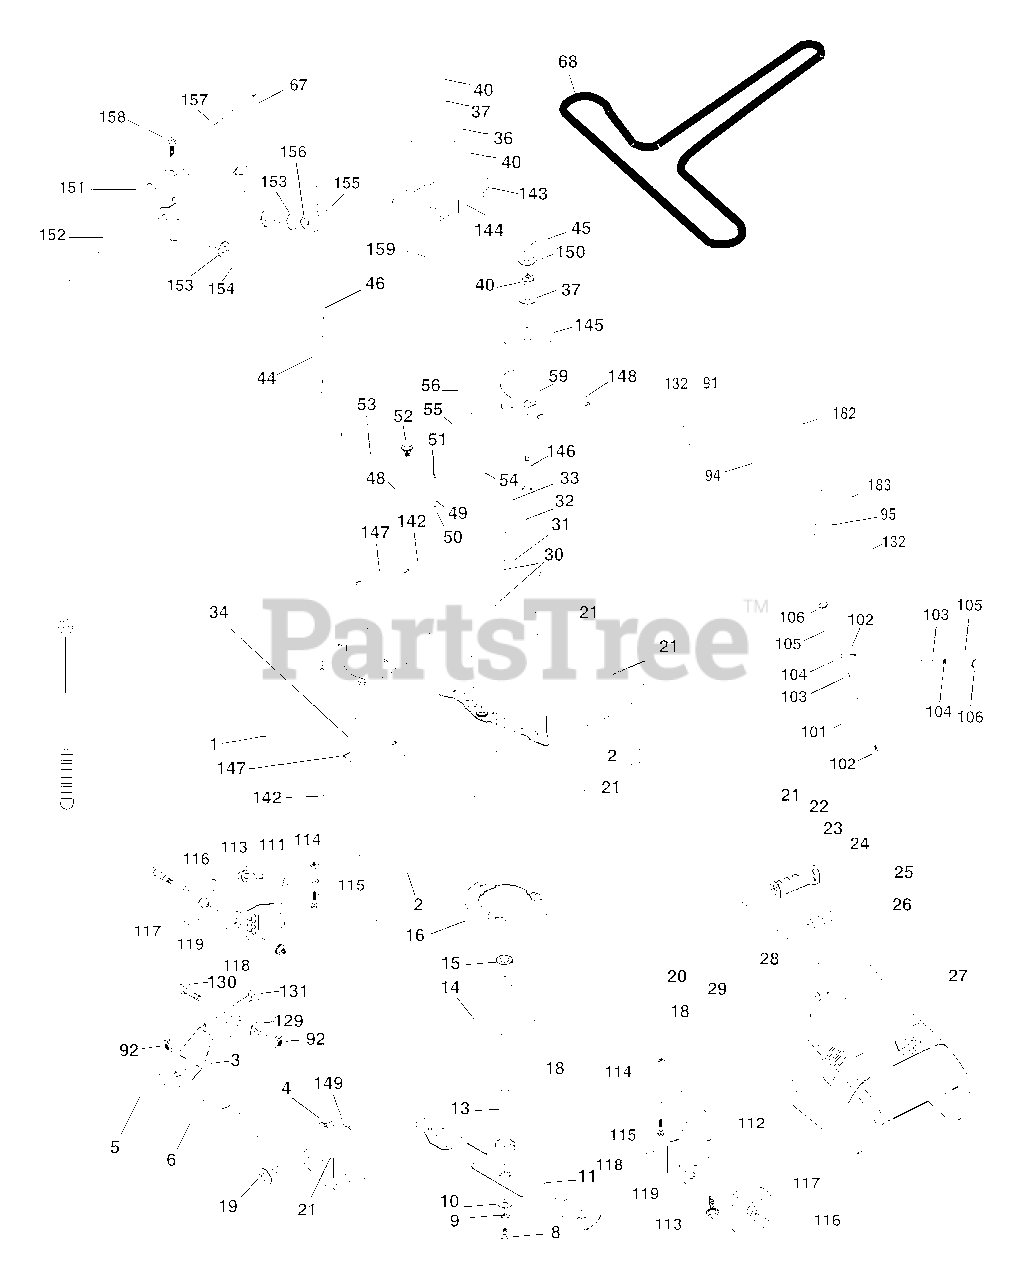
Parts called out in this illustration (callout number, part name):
1	Mower Deck Assembly, 42"
2	Bolt
3	Bracket Asm Fr. Sway Bar 3/42
4	Bracket Asm Deck 42" Sway Bar
5	Retainer Spring
6	Bar Sway Deck
8	Bolt 3/8-24 x 25 Grade 8 patched
9	Washer, Lock
10	Washer, Hardened
11	Blade, Mulching 42" Std
11	Blade Mower 42" Hi-Lift Std
13	Shaft Assembly, Mandrel, Vented
14	Housing, Mandrel, Vented
15	Bearing, Ball, Mandrel
16	Stripper, Mandrel Deck
18	Bolt, Carriage 5/16-18 x 5/8
19	Bolt, Shoulder
20	Baffle, Vortex
21	Nut
22	Stiffener Bracket
23	Bracket, Deflector Mower 42"
24	Cap, Sleeve 80 x 112 Blk Mower
25	Spring, Torsion, Deflector 2 52
26	Nut, Push Phos & Oil
27	Shield, Deflector 42" Blk
28	Washer 11/32 x 5/8 x 16 Gauge
29	Rod, Hinge 42" 6 75 W/G
30	Screw Thdrol
31	asher, Spacer Mower Vented
32	Pulley, Mandrel
33	Nut, Toplock
34	Bolt
36	Pulley, Idler, Flat
37	Washer 13/32 x 13/16 x 16 Gauge
40	Nut
44	Guard, Mandrel, LH
45	Retainer
46	Screw, Thdrol 1/4-20 x 5/8 T
48	Washer, Hardened
49	Roller Assembly, Cam Follower
50	Bolt, Shoulder #10-24 Grade 5
51	Locknut
52	Bolt, Shoulder 5/16-18 UNC
53	Arm Assembly, Pad, Brake
54	Washer, Hardened
55	Arm, Idler
56	Spacer, Retainer
59	Guard TUV Idler
67	Knob Round
68	V-Belt, 42" Mower
91	Bracket Asm Noseroller LH
94	Roller Nose 38 & 42
95	Bracket Asm Noseroller RH
101	Mulcher Cover
102	Screw, Pan Hd Phillip 10-24 x 5/8
103	Washer, Flat
104	Washer, Lock
105	Latch Assembly
106	Nut, Weld
111	Bracket, Gauge, Wheel LH
112	Bracket, Gauge, Wheel RH
113	Screw 3/8-16 x .625
116	Bolt, Shoulder
117	Wheel, Gauge
118	Nut Centerlock 3/8-16
119	Washer 3/8 x 7/8 x 14 Ga.
132	Screw 3/8-16 x .75
142	Arm Spring Brake Mower
143	Bracket Arm Idler 42"
144	Keeper Belt 42" Clutch Cable
145	Pulley Idler Flat
146	Bolt Carriage Idler
147	Spring Extension
148	Spring Return Idler
149	Retainer Spring Yellow
150	Washer 9/32 x 3/4 x 16 Ga.
151	Bracket Clutch Cable
152	Clutch Cable 42"
153	Washer Flat 3/8" Type B
154	Spring Retainer
155	Spring Retention LVR CLTCH CAB
156	Spacer Clutch Cable
157	Rod Clutch Cable 3/8"
158	Screw Hex Thd Cut 1/4-20 x 5/8
159	Bolt Rdhd Sqn 3/8-16 UNC x 1-3/4
182	Rod Roller Nose
183	Retainer Spring
